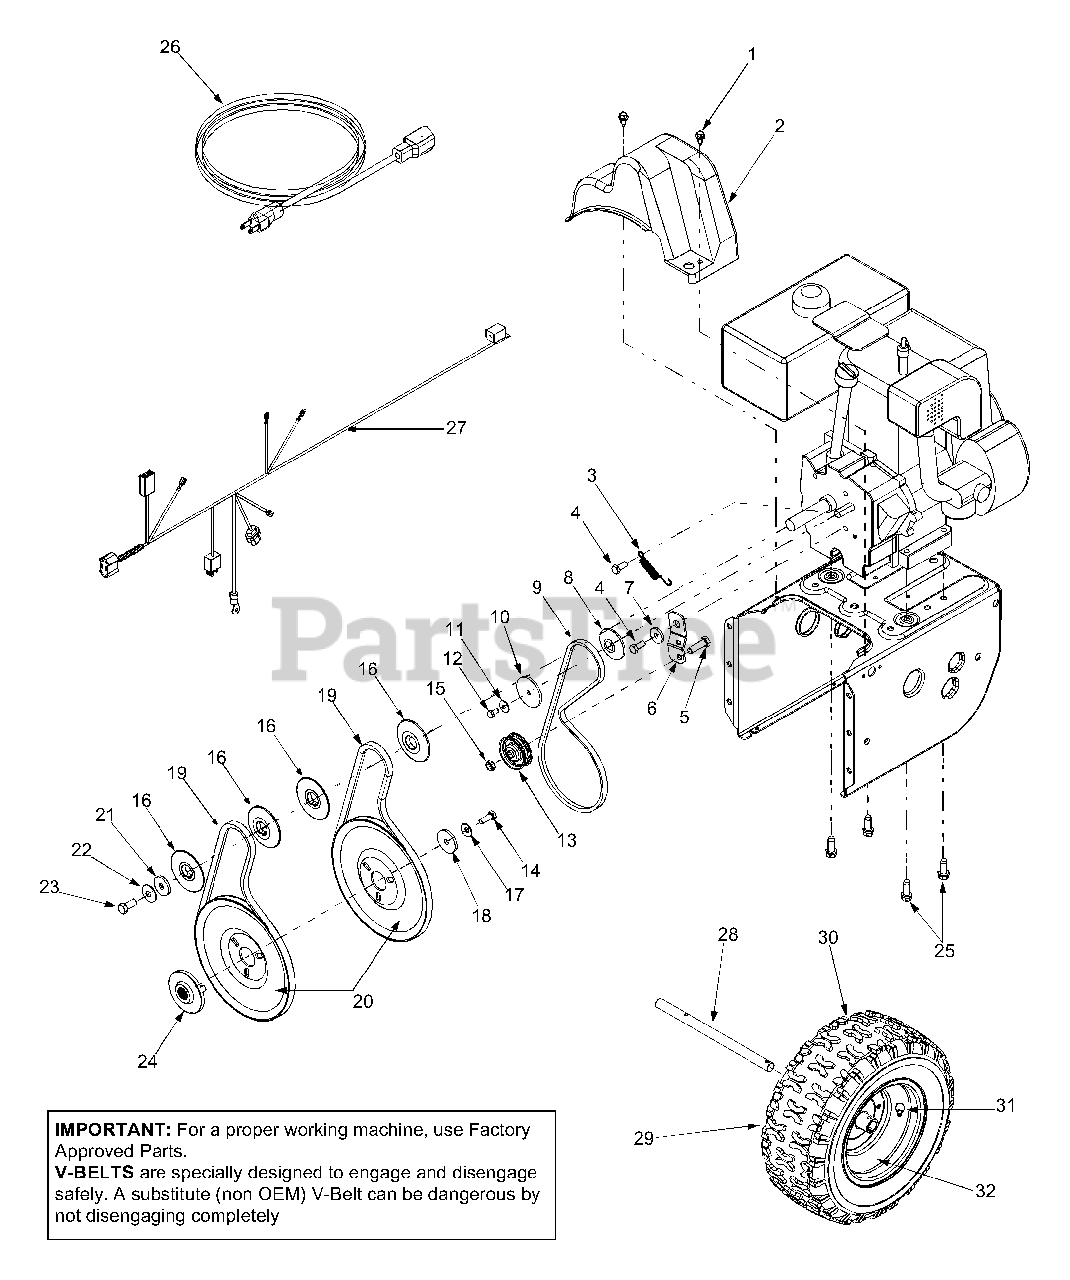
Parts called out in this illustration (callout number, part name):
1	Hex Washer Screw 1/4-20 x .625
2	Belt Cover
3	Extension Spring
4	Hex Screw 5/16-24 x .75
5	Hex Cap Screw 3/8-16 x 1.25
8	Pulley Half
9	V-Belt
10	Pulley Half
11	Bell Washer
12	Hex Cap Screw 1/4-28 x .50
13	Flat Idler
14	Lock Hex Cap Screw 5/16-24
15	Lock Jam Nut 3/8-16
16	Pulley Half
17	Bell Washer
18	Flat Washer
19	Belt
20	Auger Pulley
21	Flat Washer 3/8 x 1.25 OD
22	Bell Washer
23	Hex Cap Screw 3/8-24
24	Adapter Pulley
25	Hex Screw 3/8-16 x 1.0
26	Extension Cord
27	Upper Harness Assembly
28	Axle 16"
30	Tire 16 x 6.5 x 8
31	Tubeless Air Valve
